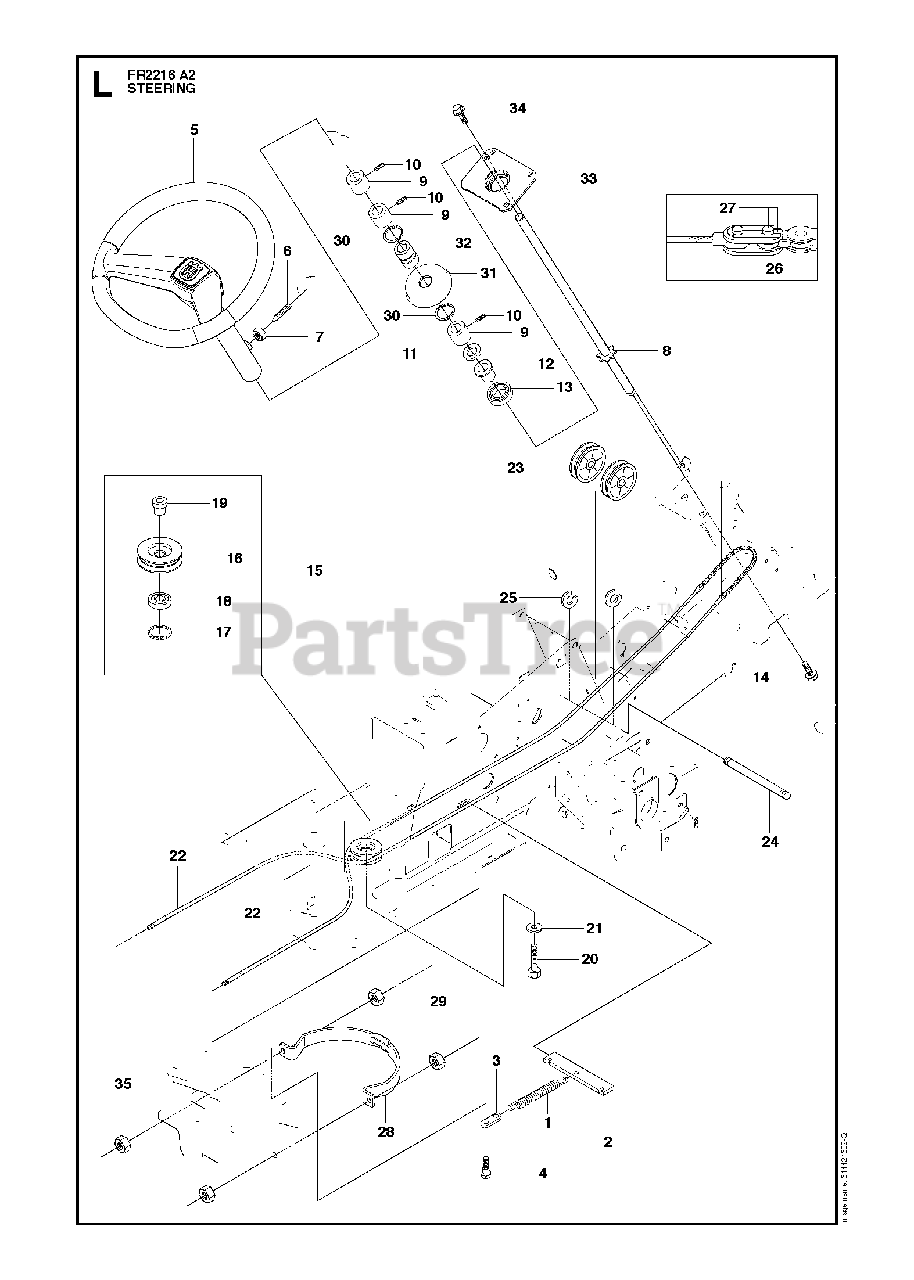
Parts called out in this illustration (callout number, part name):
2	SPRING BRACKET
3	CONNECTOR
7	NUT
13	BALL BEARING 6004-2RS1
16	ROLLER
17	CIRCLIP SGH 47
18	BALL-BEARING 6204-2RS
19	BUSHING
22	RP STEERING CABLE COMPLETE
25	RETAINING RING
26	STEERING CHAIN
28	WIRE GUIDE
30	RETAINING RING SGA 25
